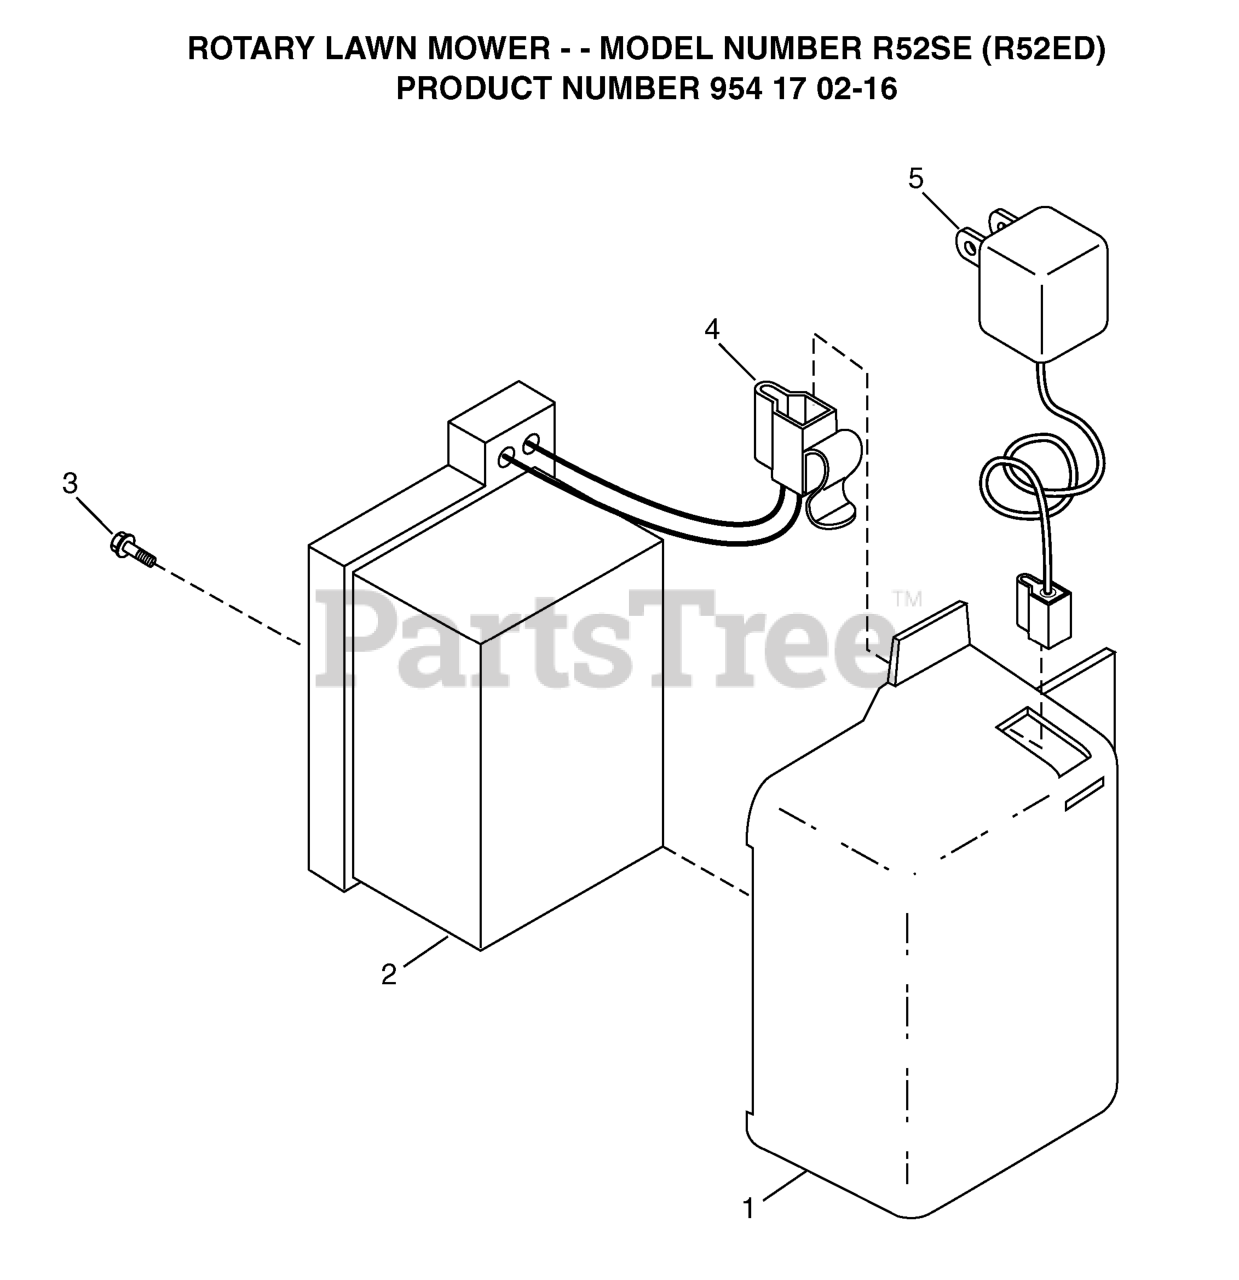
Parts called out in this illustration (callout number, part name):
2	KIT BATTERY REPL
3	SCREW.HX.13X.750
4	CONNECTOR PM
5	BATTERY CHARGER
